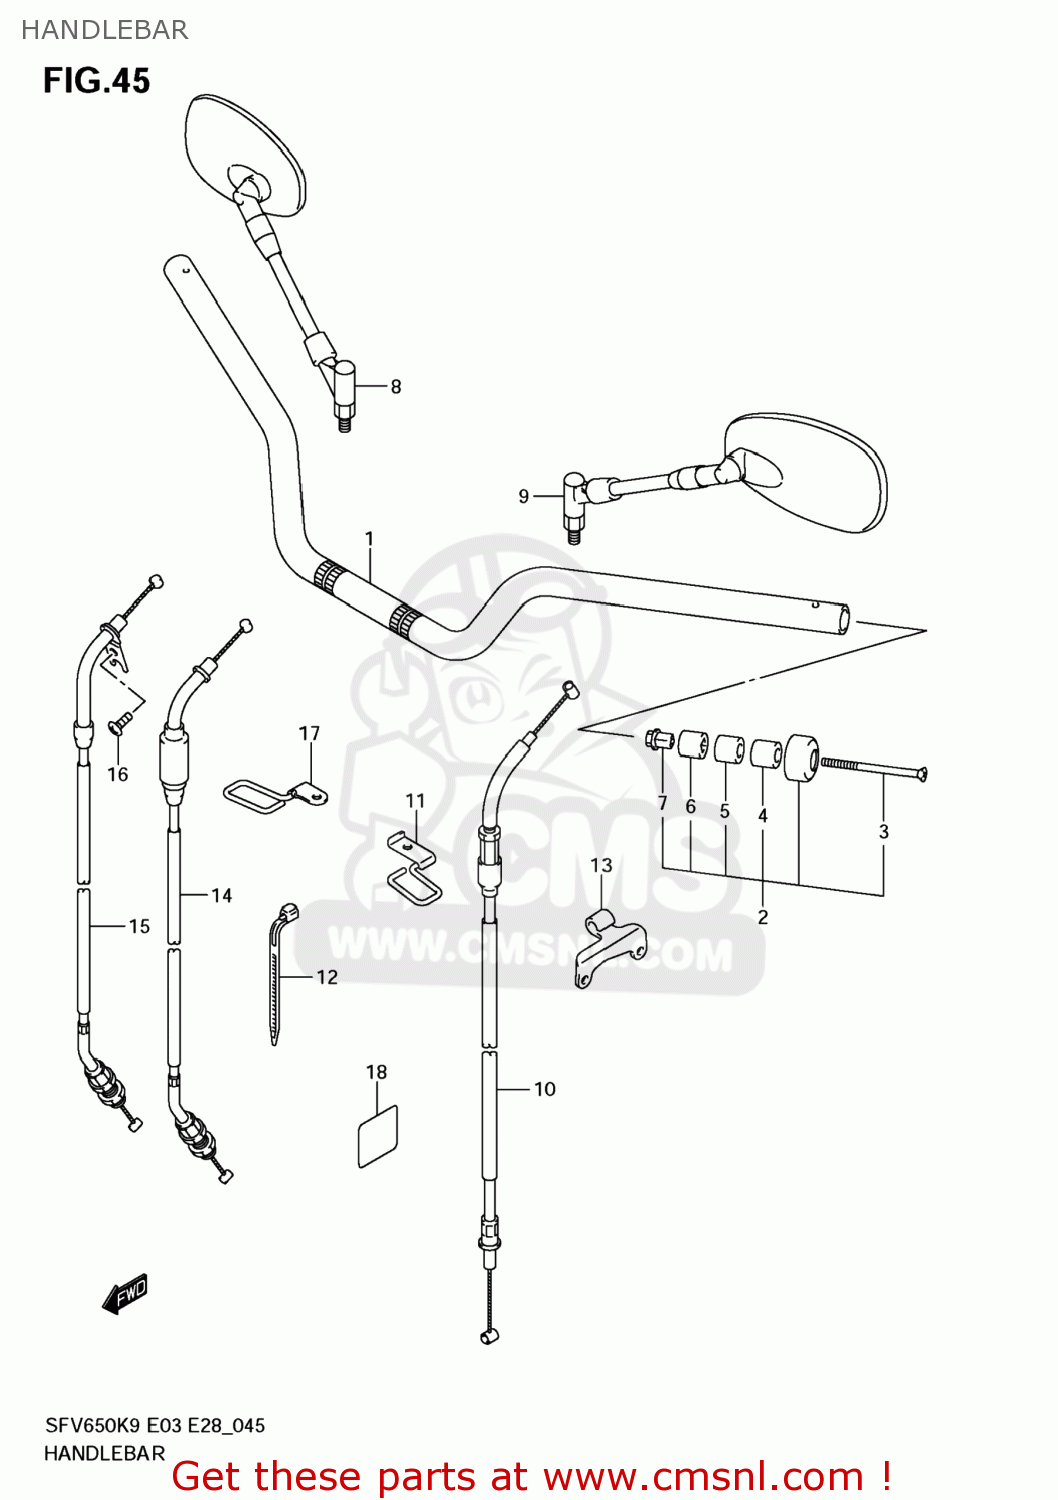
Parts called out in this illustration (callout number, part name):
1	HANDLEBAR
2	BALANCER SET,HANDLEBAR
3	SCREW
4	EXPANDER,HANDLE BALANCER
5	SPACER(6.5X16X15)
6	EXPANDER,HANDLE BALANCER
7	NUT,HANDLE BALANCER
8	MIRROR ASSY,RR VIEW
9	MIRROR ASSY,RR VIEW,L
10	CABLE ASSY,CLUTCH
11	GUIDE,CLUTCH CABLE
12	CLAMP(L:165)
13	STOPPER,CLUTCH CABLE
14	CABLE ASSY,THROTTLE NO.1
15	CABLE ASSY,THROTTLE NO.2
16	SCREW(5X10)
17	GUIDE,THROTTLE CABLE NO.1
18	PROTECTOR
